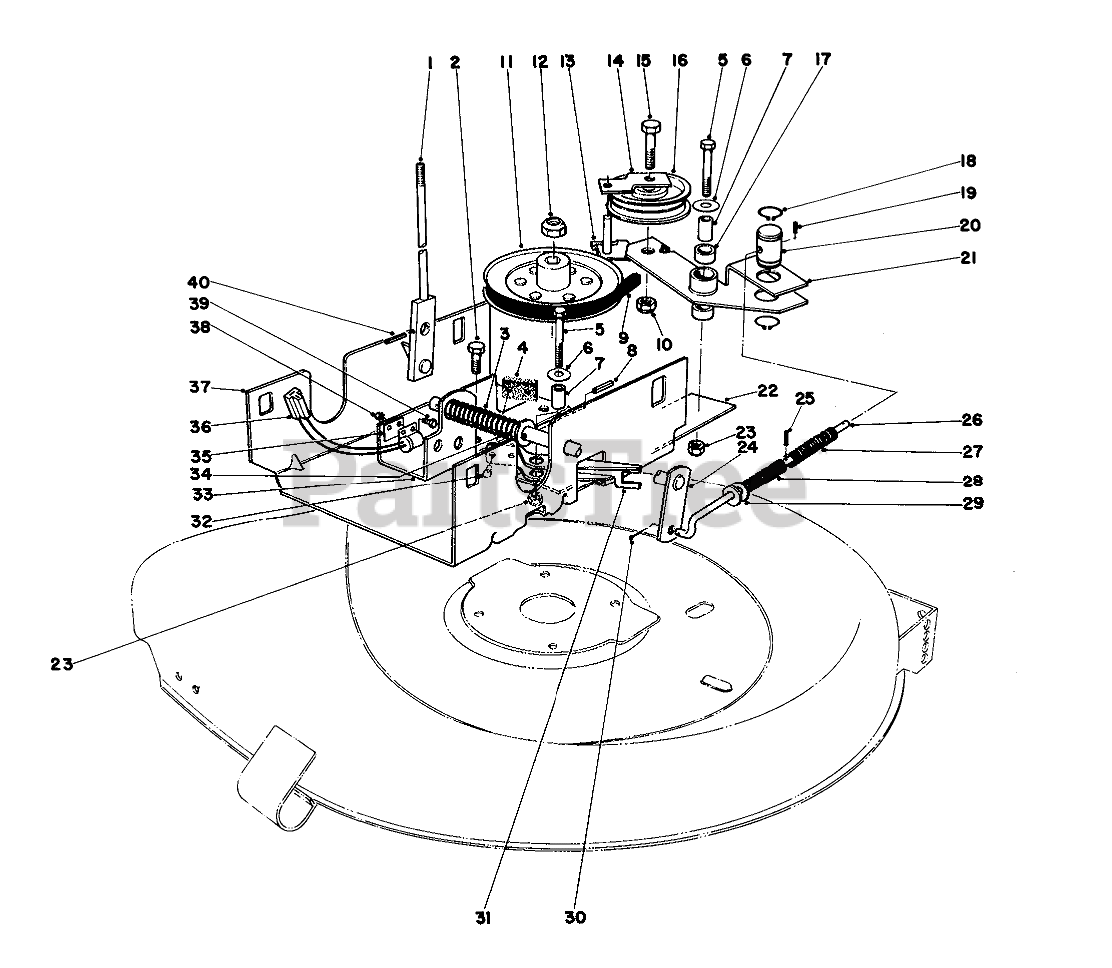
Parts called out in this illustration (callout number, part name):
1	Lever Deck Engagement
2	SCREW-HH
3	COMP SPRING O
4	BLADE BRAKE LINING
5	SCREW-HH
6	WASHER-PLAIN
7	PIVOT SPACER
8	Pin-Roll
9	V-BELT
10	NUT-LOCK, SIDE
11	DECK PULLEY R
13	Belt Retainer
14	BELT RETAINER UPPER
15	SCREW-HH
16	Flat Idler
17	Bushing
18	RING-RETAINING
19	PIN-ROLL
20	Pin-Pivot
21	Idler Arm (Incl. Ref. #17)
22	Bracket Idler Mounting
23	NUT-LOCK, CONE
24	Linkage
25	PIN-SPRING
26	BLADE ENGAGE ROD
27	Spring Deck Idler
28	Spring Deck Brake
29	WASHER
30	PIN-COTTER
31	Blade Brake (Incl. Ref. #4 & 32)
32	Rivet
33	Mounting Bracket Blade
34	WASHER-FLAT
35	Spacer Switch
36	DECK INTERLOCK SWITCH
37	CHANNEL HT ADJ R
38	NUT-KEPS
40	PIN-SPIRAL
